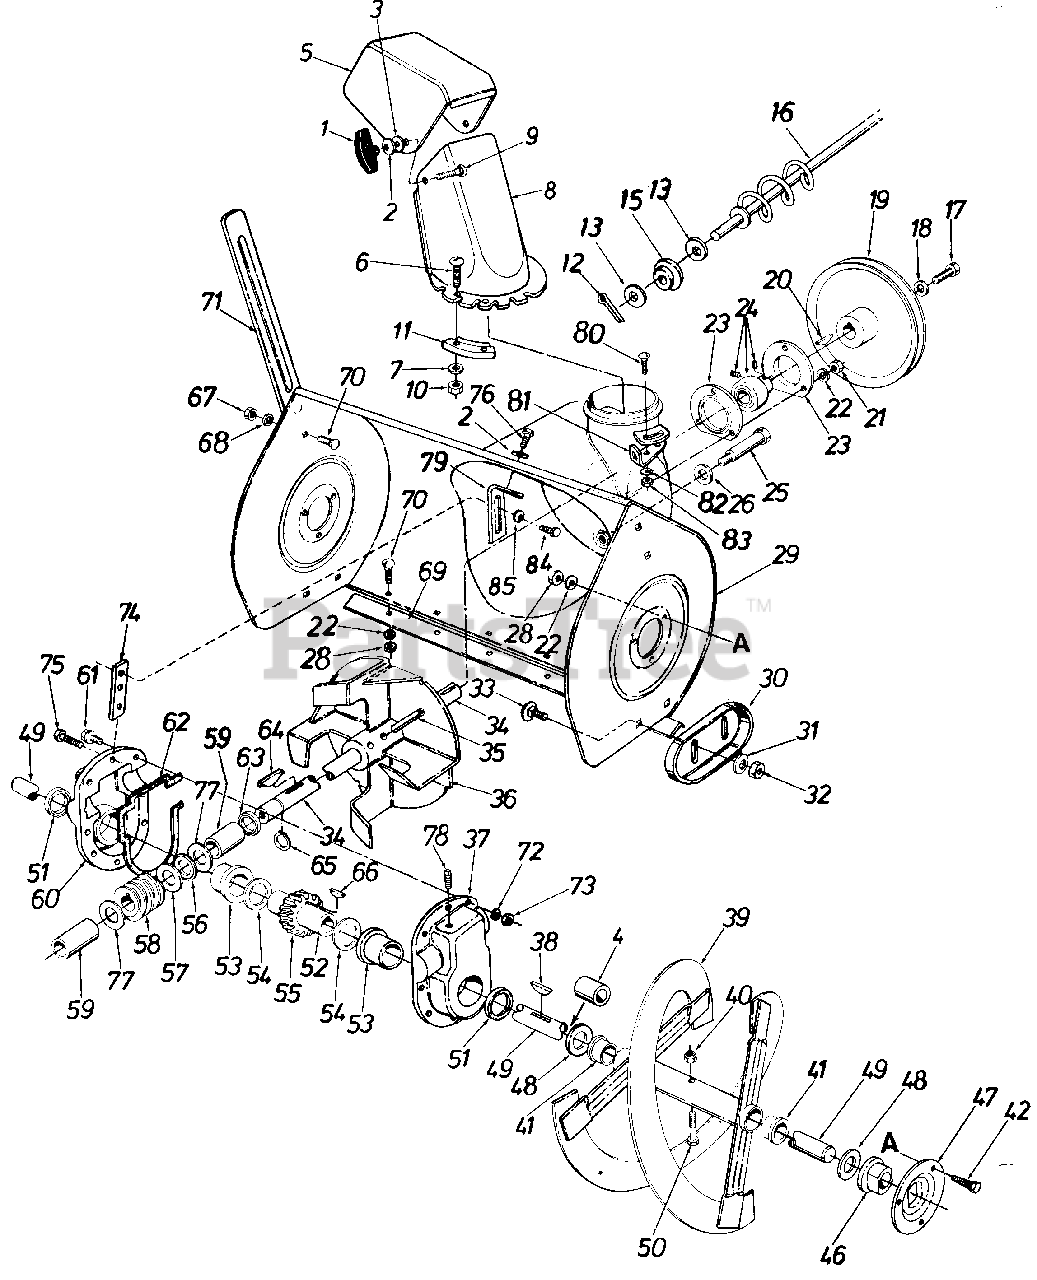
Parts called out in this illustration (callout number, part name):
1	Hand Knob Ass'y.
2	Bell-Wash. .345 I.D. x .88 O.D. x .060
3	Fl. Wash. .312 I.D. x 1.125 O.D. x .125
4	Spacer
5	Top Chute
6	Truss Mach. Scr. 1/4-20 x .75"
7	Fl-Wash. 1/4" I.D.
8	Chute
9	Carr Bolt 5/16-18 x 1.00" Lg.
10	Hex Cent. L-Nut 1/4-20 Thd.
11	Chute Flange Keeper
12	Coter Pin
13	Fl-Wash. .385" I.D. x .62"
15	Bushing
16	Chute Crank Ass'y.
17	Hex L-Scr. 5/16-18 x .88" Lg.
18	Bell-Wash. .345 I.D. x .88
19	V-Pulley .875 I.D. x 10.12
20	#9 Hi-Pro Key 3/16 x 3/4" Dia
21	Hex Nut 5/16-18 Thd.
22	L-Wash. 5/16" I.D.*
23	Bearing Hsg.Self Aligning Brg.
24	Self Aligning Brg. .875 I.D.
25	Stud 3/8-16 x 2.75" Lg.
26	Bell-Wash. .400 I.D. x .88 O.D. x .060
28	Hex Nut 5/16-18 Thd.
29	Blower Hsg. Ass'y.
30	Slide Shoe
31	Bell-Wash. .400 I.D. x .88 O.D. x .060
32	Hex Jam Nut 3/8-16 Thd.
33	Carr. Bolt 3/8-16 x .62" Lg.
34	Blower Axle
35	Spring Pin Spiral 5/16" Dia. x 1.75" Lg.
38	#91 Woodruff Key 1/4" x 3/4" Dia.
40	Hex Ins. L-Nut 5/16-18 Thd.
41	Plastic Bushing
42	Hex Sems Scr. 5/16-18 x .75"
46	Flange Brg. w/Flats 1.0" I.D.
47	Bearing Hsg.Spiral Hsg.
48	Fl-Wash. 1.06 I.D. x 1.75" O.D. x .100
49	Spiral Axle-
50	Hex Bolt 5/16-18 x 1.75" Lg.
51	Oil Seal 1.50" I.D.
52	Worm Gear Shaft
53	Flange Brg. 1.503 I.D.
54	Fl-Wash. 1.5 I.D. x 2.0 O.D.
55	Double Threaded Worm Gear
56	Thrust Brg. .88 I.D. x 1.44 O.D. x .078
57	Fl-Wash. .88 I.D. x 1.40 O.D.
58	Double Threaded Worm- L.H.
59	Sleeve Brg. .875 I.D.
60	Complete Gear Hsg. Half- R.H.
61	Hex Bolt 5/16-18 x 1.0" Lg.
62	Gasket
63	Oil Seal .875" I.D.
64	#9 Hi-Pro Key 3/16 x 3/4" Dia.
65	Snap Ring-.875" Dia.
66	#91 Woodruff Key 1/4 x 3/4" Dia.
67	Hex Nut 5/16-18 Thd.
68	L-Wash. 5/16" I.D.
70	Carr. Bolt 5/16-18 x .62" Lg.
71	Drift Cutter
72	Wave Wash. 5/16" I.D.
73	Hex Ins. L-Nut 5/16-18 Thd.
74	Gear Hsg. Support Plate
75	Hex Bolt 5/16-18 x 1.25"
76	Hex Wash. Hd. Self-Tap Scr. 5/16-18 x .75" Lg.
77	Fl-Wash. .88 I.D. x 1.40 O.D.
78	Filler Plug
80	Carr. Bolt 5/16-18 x .75" Lg.
82	Bell-Wash. .345 I.D. x .88"
83	Hex Nut 5/16-18 Thd.
84	Hex Bolt 1/4-28 x .75" Lg.
85	Bell-Wash. .28" I.D. x .75" O.D.
